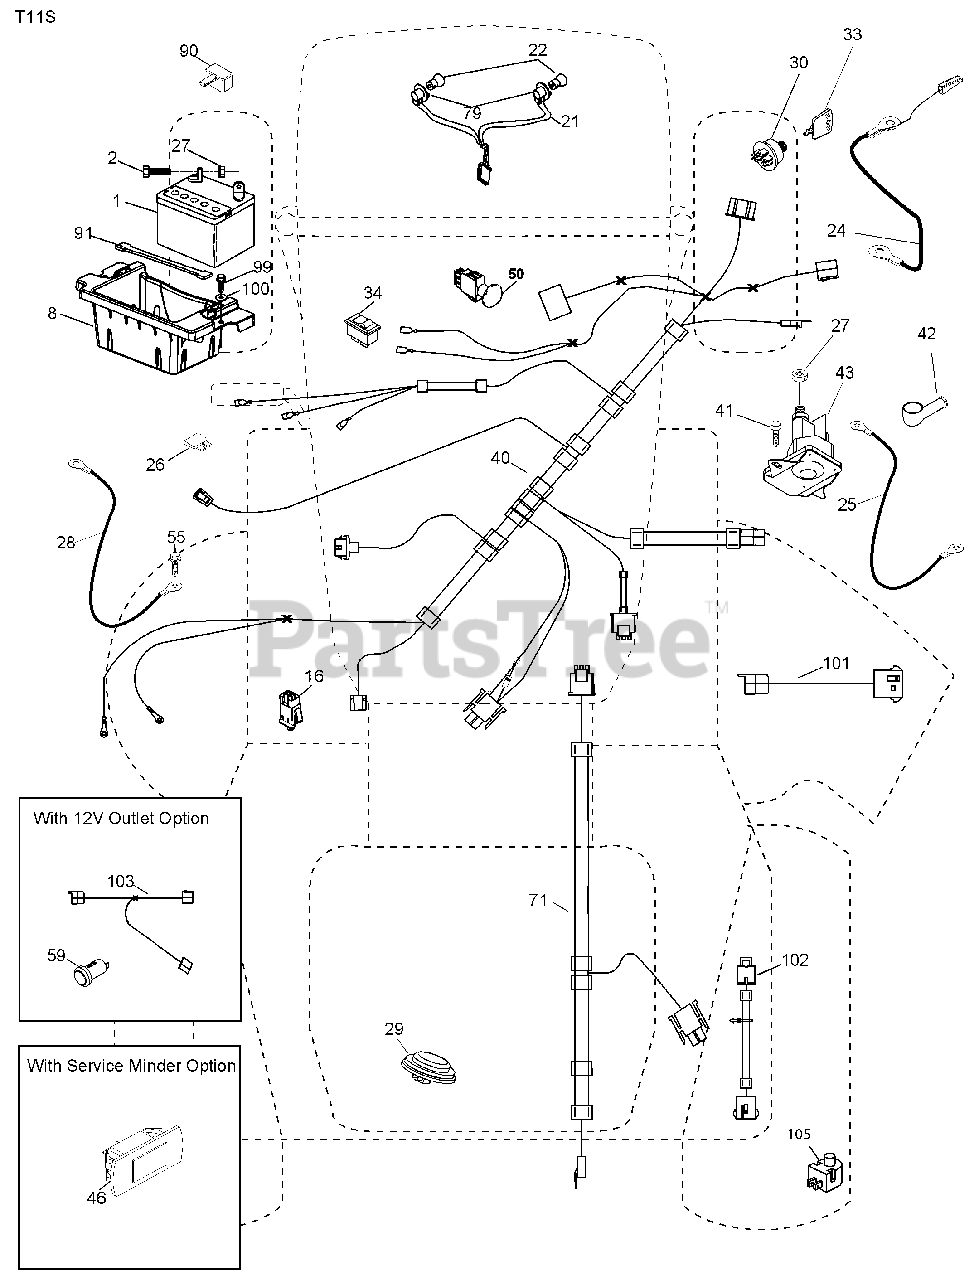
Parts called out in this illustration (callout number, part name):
1	Battery
2	Bolt Hex Head 1/4-20 x 3/4
8	Box Battery
16	Switch Interlock Push-In
21	Harness Socket Light W/4152J
22	Bulb Light
24	Cable Battery
25	Cable Starter
27	Nut Keps Hex 1/4-20 unc
28	Cable, Ground
29	Switch, Seat
30	Switch, Ign
34	Switch Light / Reset
40	Harness Ign. Dash
41	Screw Thd Cut 1/4-20 x 1/2
42	Cover, Terminal
43	Solenoid
46	Gauge Servicereminder Hrmtr
50	Switch PTO
55	Screw Thdrol 5/16-18 x 3/4 TYTT
59	Outlet 12-Volt
71	Harness Ign.
79	Socket Asm Bulb Twistlock
90	Cover Terminal
91	Strap Battery Mount
99	Screw Hexwsh Thdrol 1/4-20 x 3/4
100	Washer 9/32 x 7/8 x 16 Ga.
101	Harness Pigtail
102	Harness Pigtail
103	Harness 12-Volt Pigtail
105	Switch Reverse TT Pedal Control
